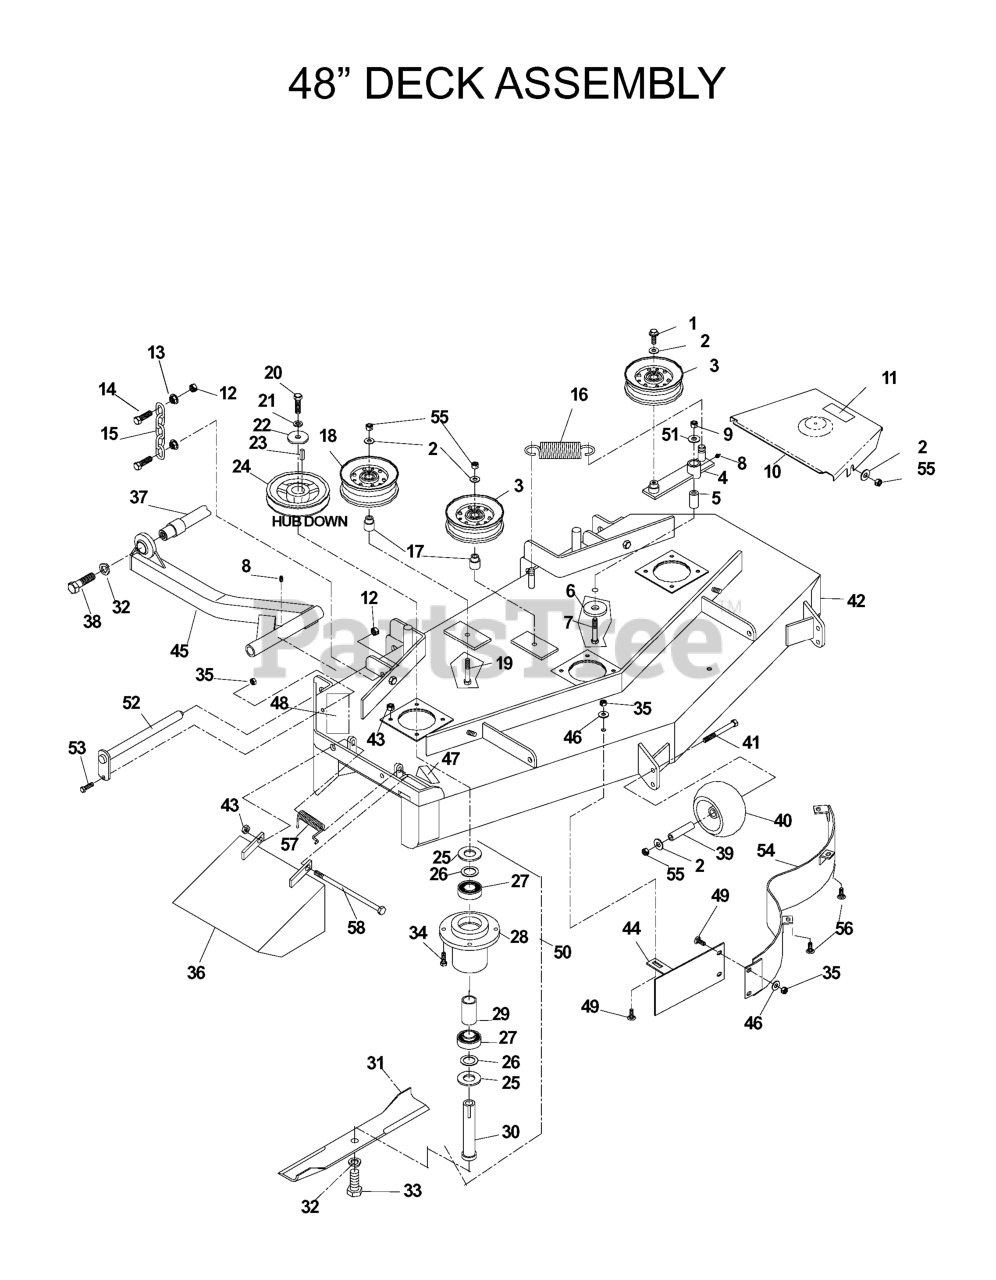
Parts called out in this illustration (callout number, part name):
1	4CS 3/8C X 1 SERRATED HEAD
2	WASHER 3/8 FLAT
3	IDLER PULLEY
5	PIVOT BUSHING
6	WASHER, SUPPORT
7	HCS 1/2C X 3 1/4
8	ZERK
9	NUT 1/2-13 HEX NYLOC ZD
10	48 BELT SHIELD
11	DECAL, NO STEP
12	NUT 7/16C CENTERLOCK
13	NUT 7/16C WHIZ
14	HCS 7/16C X 1 1/2
15	LIFT CHAIN
17	IDLER BUSHING
18	IDLER PULLEY (TALL)
19	SCREW 3/8C X 2 3/4 HEX CAP
20	HCS 7/16F X 1 1/2
21	WASHER 7/16 LOCK
22	SPINDLE WASHER
23	KEY 1/4 SQ X 1 1/8
25	MACHINERY BUSHING 10 GA.
26	BUSHING.MACHINE.18.GAUGE
27	BEARING
28	HOUSING, DIE CAST
30	SPINDLE SHAFT
31	BLADE OEM 16 1/4"
32	LOCKWASHER 5/8
33	HCS 5/8F X 1 1/4
34	HCS 5/16C X 1 1/4
35	NUT 5/16C CENTERLOCK
36	CHUTE 48"
37	STRUT MOUNT WELDMENT
38	HCS 5/8C X 2 GR.5
40	ANTI-SCALP ROLLER
41	HCS 3/8C X 3 1/2
42	DECK W/DECALS 48"
43	NUT 5/16 NYLOC
44	CENTER BAFFLE 48"
45	STRUT WLDMT - RT
46	WASHER 5/16 FLAT
47	DECAL, CPSC
48	DECAL, DANGER
49	CARRIAGE BOLT 5/16C X 5/8"
50	HOUSING, COMPLETE
51	WASHER 1/2 FLAT
53	HCS 5/16C X 3/4
54	MAIN BAFFLE - 48" DECK BLK
55	NUT 3/8-16 NYLOC
56	HCS 5/16C X 3/4
57	SPRING, TORTION
58	BOLT - 5/16 X 7
539103687	DECK BELT 48"
539104621	STRUT SLDMT-LT
